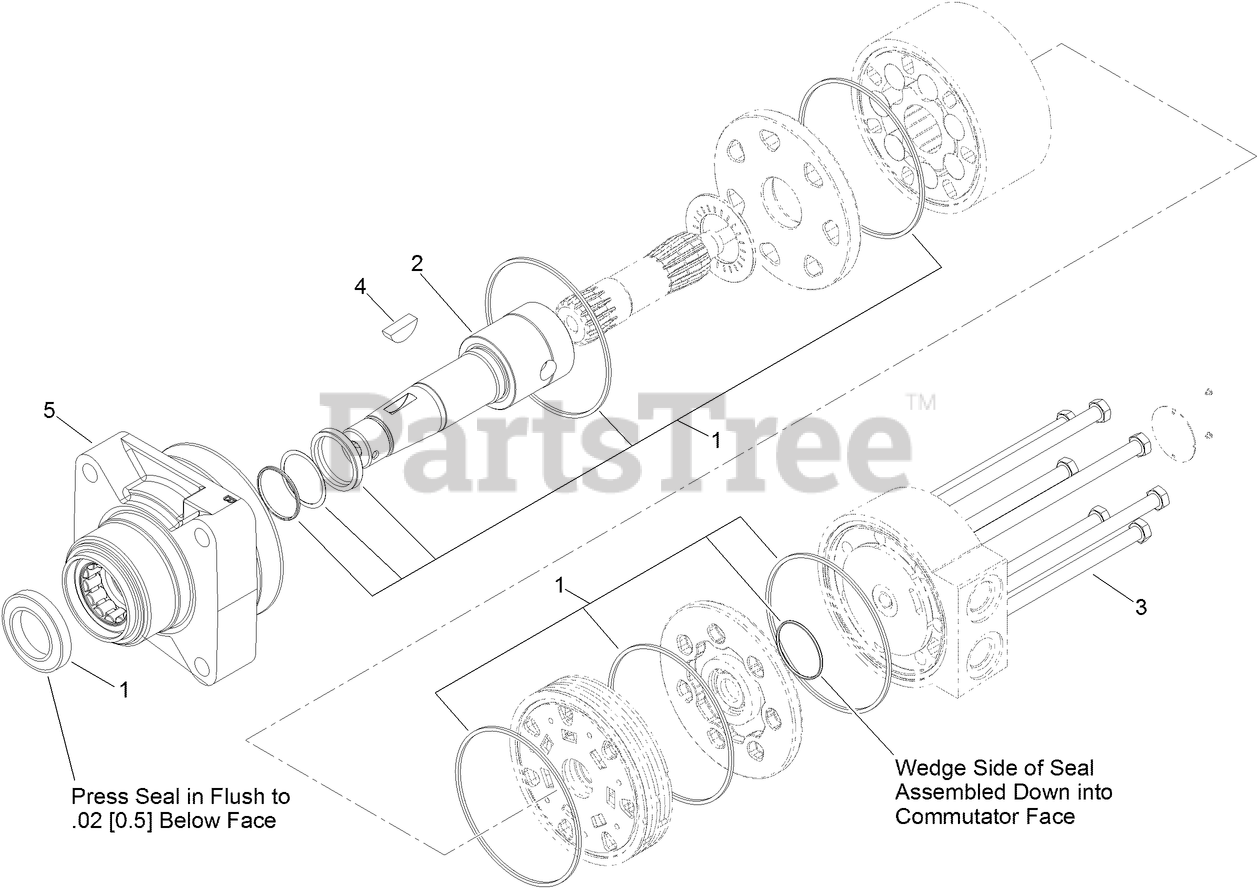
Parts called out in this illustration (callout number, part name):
1	SEAL KIT
2	COUPLING-SHAFT
3	SCREW-HH
4	KEY-WOODRUFF
5	MOTOR HOUSING ASM
